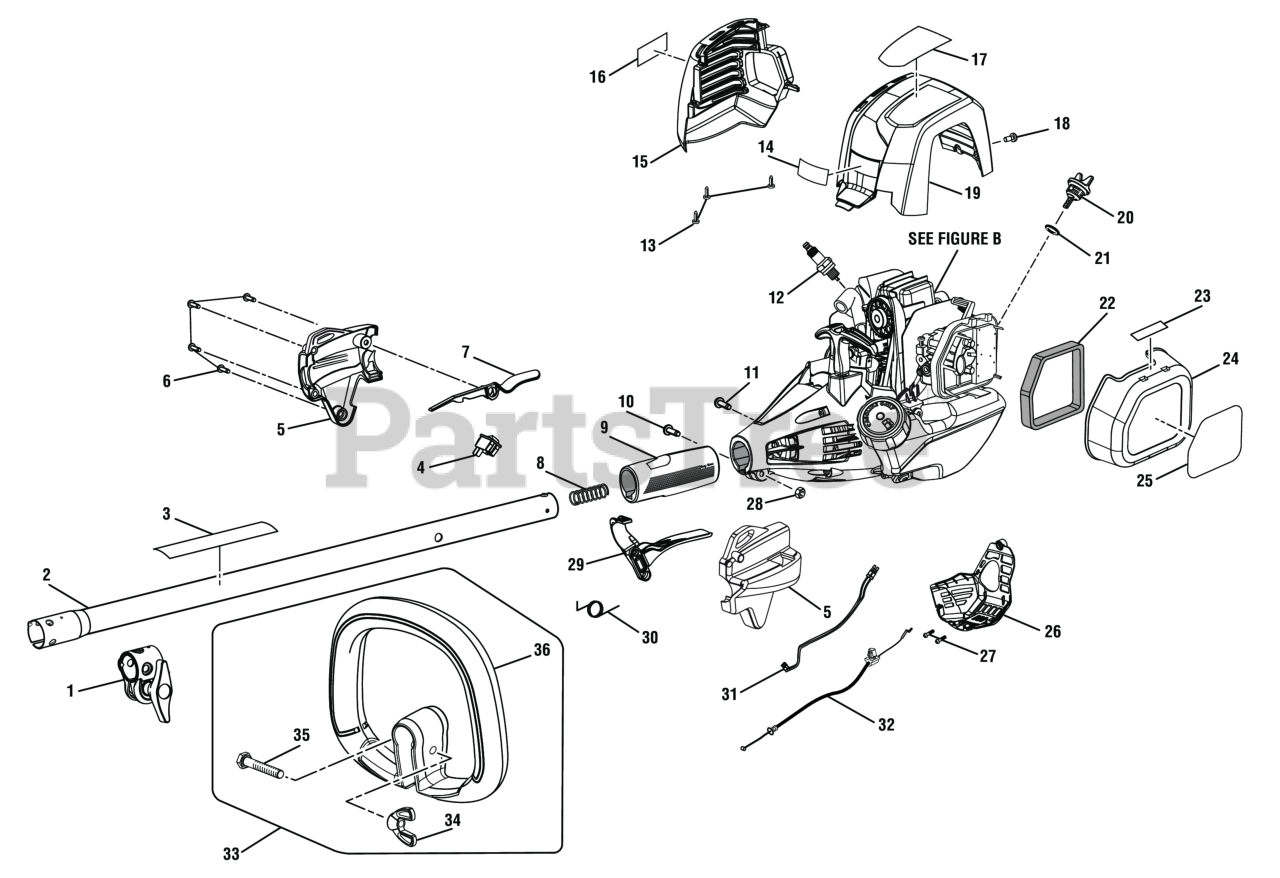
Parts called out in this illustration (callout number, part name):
1	Boom Clamp Assembly
2	Upper Boom Assembly
3	Warning Icon Label
4	Stop Switch (Momentary Contact)
5	Control Handle Assembly (Inc. Key No. 6)
6	Screw (M4 x 20 mm, T20 Torx Pan Hd. S.T.)
7	Trigger Lock
8	COMPRESSION SPRING
9	Rear Handle Grip
10	Screw (M6 x 20 mm, T27 Torx Button Hd.)
11	Screw (M4 x 8 mm, T25 Torx Pan Hd. T.F.)
12	Spark Plug (Champion RY4C)
13	Screw (M4 x 12 mm, T20 Torx Truss Hd.)
14	Logo Label
15	Muffler Housing (Inc. Key No. 16)
16	Warning Label (Combustion)
17	X430 Label (RY34006)
17	C430 Label (RY34426)
17	S430 Label (RY34446)
18	Shoulder Screw (M4 x 11 mm, T25 Torx Pan Hd.)
19	Top Cover
20	Oil Cap/Dipstick (Incl. key no. 12)
22	Air Filter
23	Choke Label
24	Air Filter Cover
25	Starting Label
26	CE Cover (Bottom Cover)
27	Screw (#6-19 x 1/2 in., Phillips Hd. T.F.)
28	Hex Nut (M6.3 x 1)
29	Throttle Trigger
30	Torsion Spring (Throttle Trigger)
31	Lead Assembly
32	Throttle Cable
33	Front Handle Assembly
34	Wing Nut (1/4-20, Plastic)
35	Screw (1/4-20 x 40 mm, Cap Hex Hd.)
36	Front Handle
